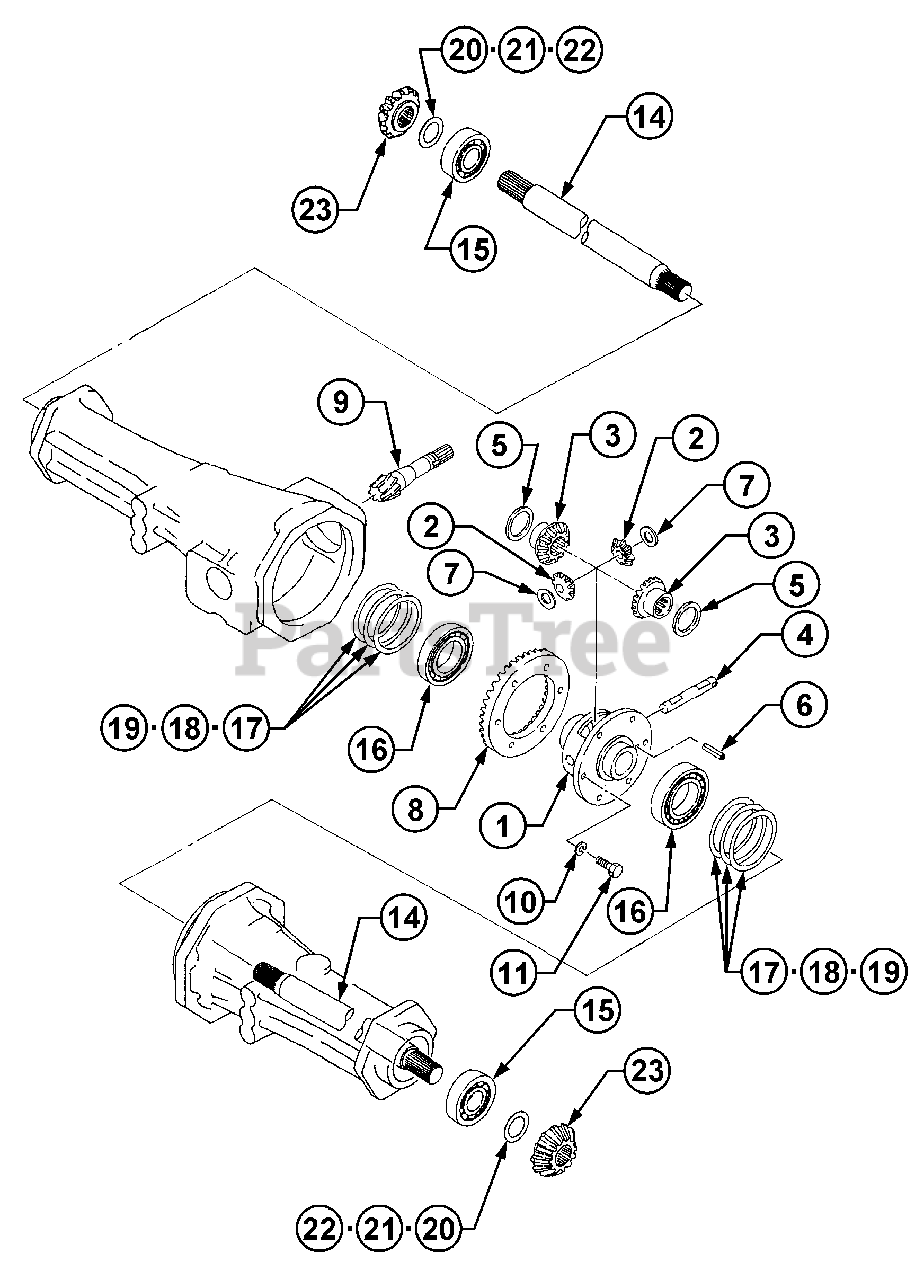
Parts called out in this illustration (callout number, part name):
4	Shaft, Pinion
5	Washer, Thrust
8	Gear, Ring
9	Shaft, Pinion
10	Washer, Spring
15	Bearing, Ball
16	Bearing, Ball
17	Liner, t=0.07
20	Liner, t=0.15
